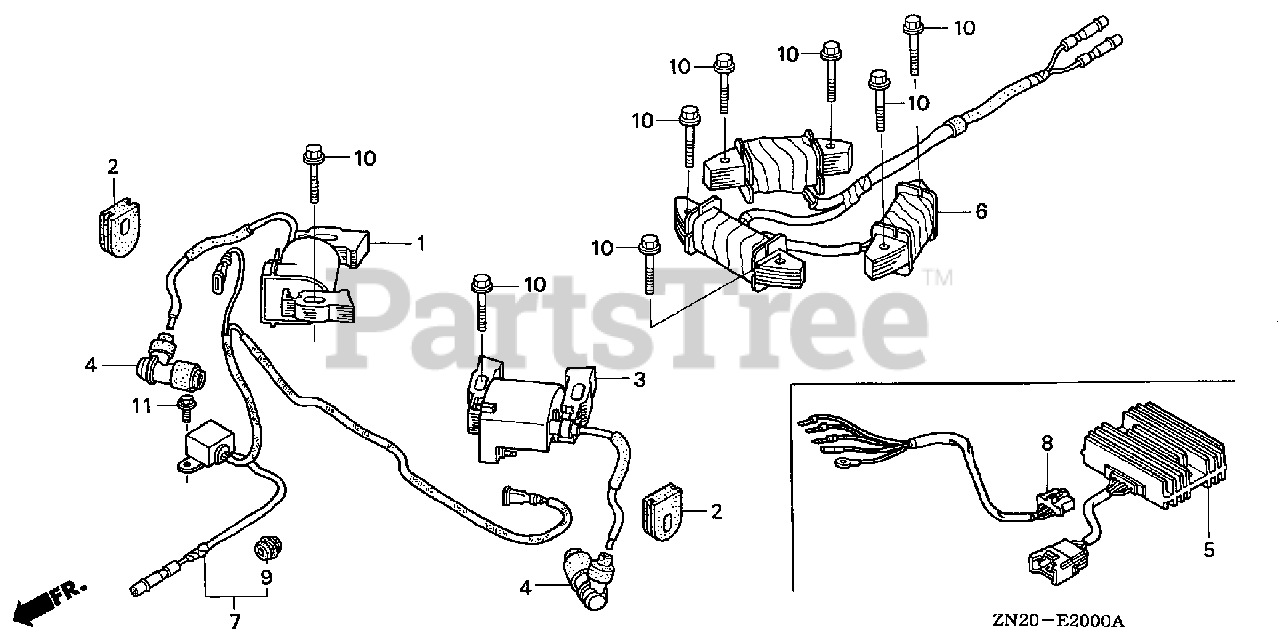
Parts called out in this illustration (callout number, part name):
1	COIL ASSY., R. IGNITION
2	GROMMET, IGNITION WIRE
3	COIL ASSY., L. IGNITION
4	CAP ASSY., NOISE SUPPRESSOR
5	RECTIFIER ASSY., REGULATOR (20A)
6	COIL ASSY., CHARGE (12V/20A)
7	DIODE ASSY., ENGINE STOP
8	SUB-WIRE HARNESS ASSY.
9	GROMMET, TOOL
10	BOLT, FLANGE (6X32)
11	BOLT, FLANGE (6X8)
